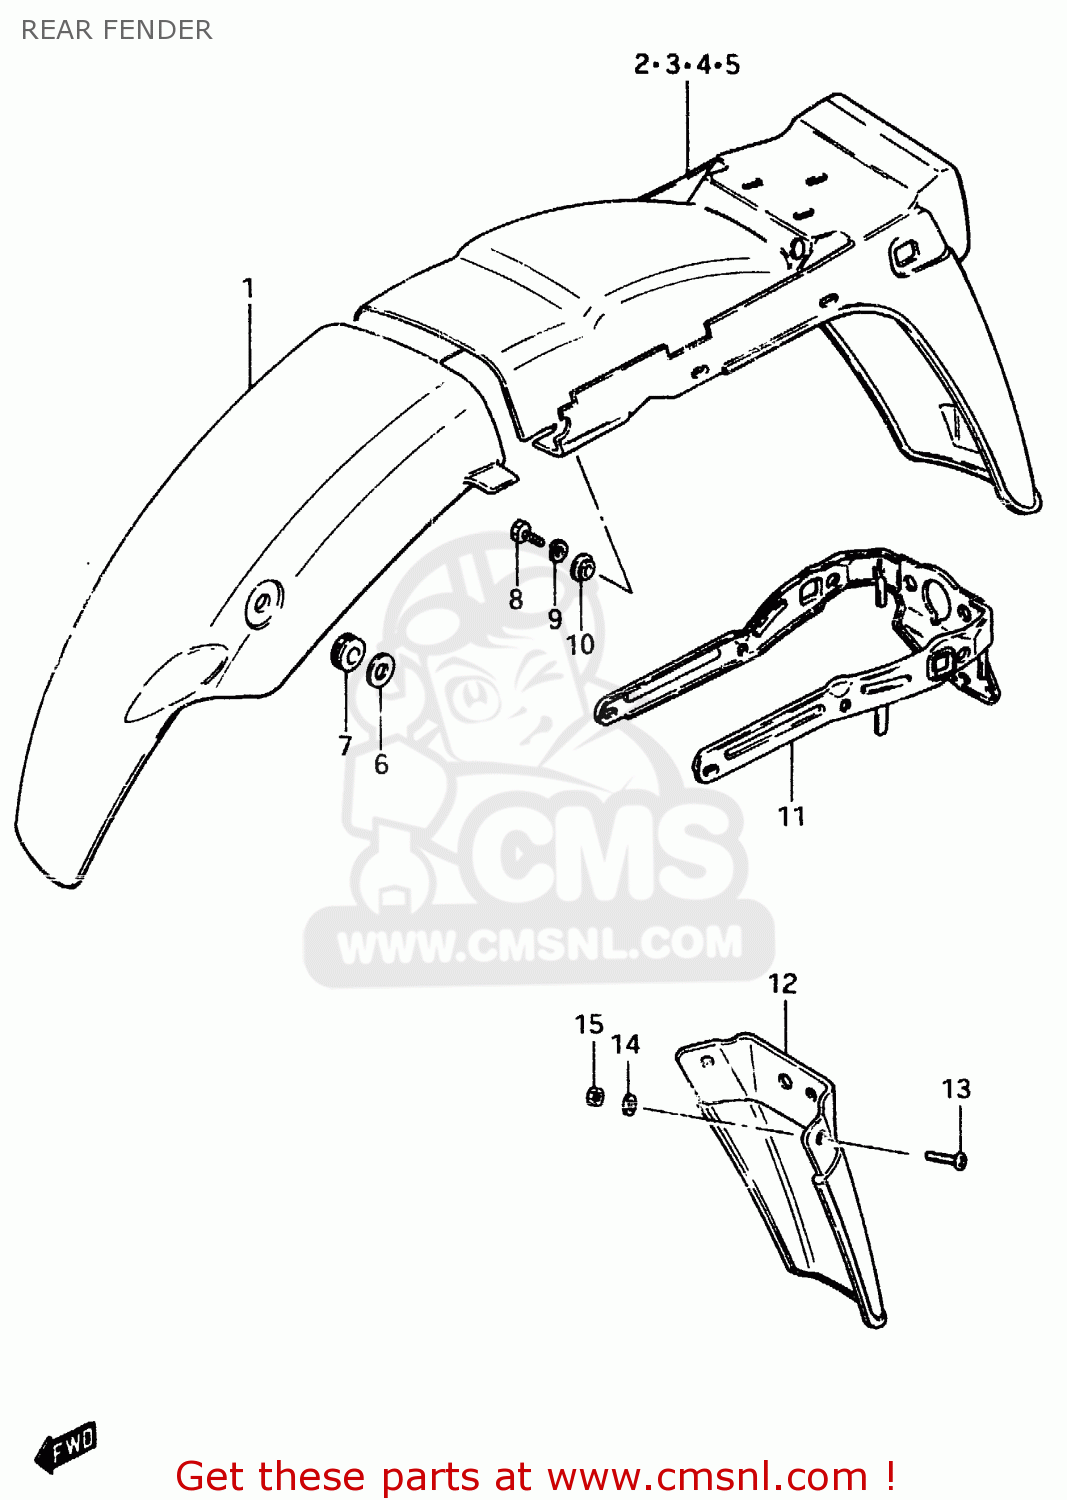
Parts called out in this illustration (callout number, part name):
1	BODY, REAR FENDER FRONT
2	FENDER, REAR
3	FENDER, REAR
4	FENDER, REAR
5	FENDER, REAR
6	WASHER
7	CUSHION
8	BOLT, UPPER
9	LOCK WASHER
10	WASHER
11	REINFORCEMENT, REAR FENDER
12	EXTENSION, REAR FENDER
13	SCREW
14	WASHER
15	NUT
